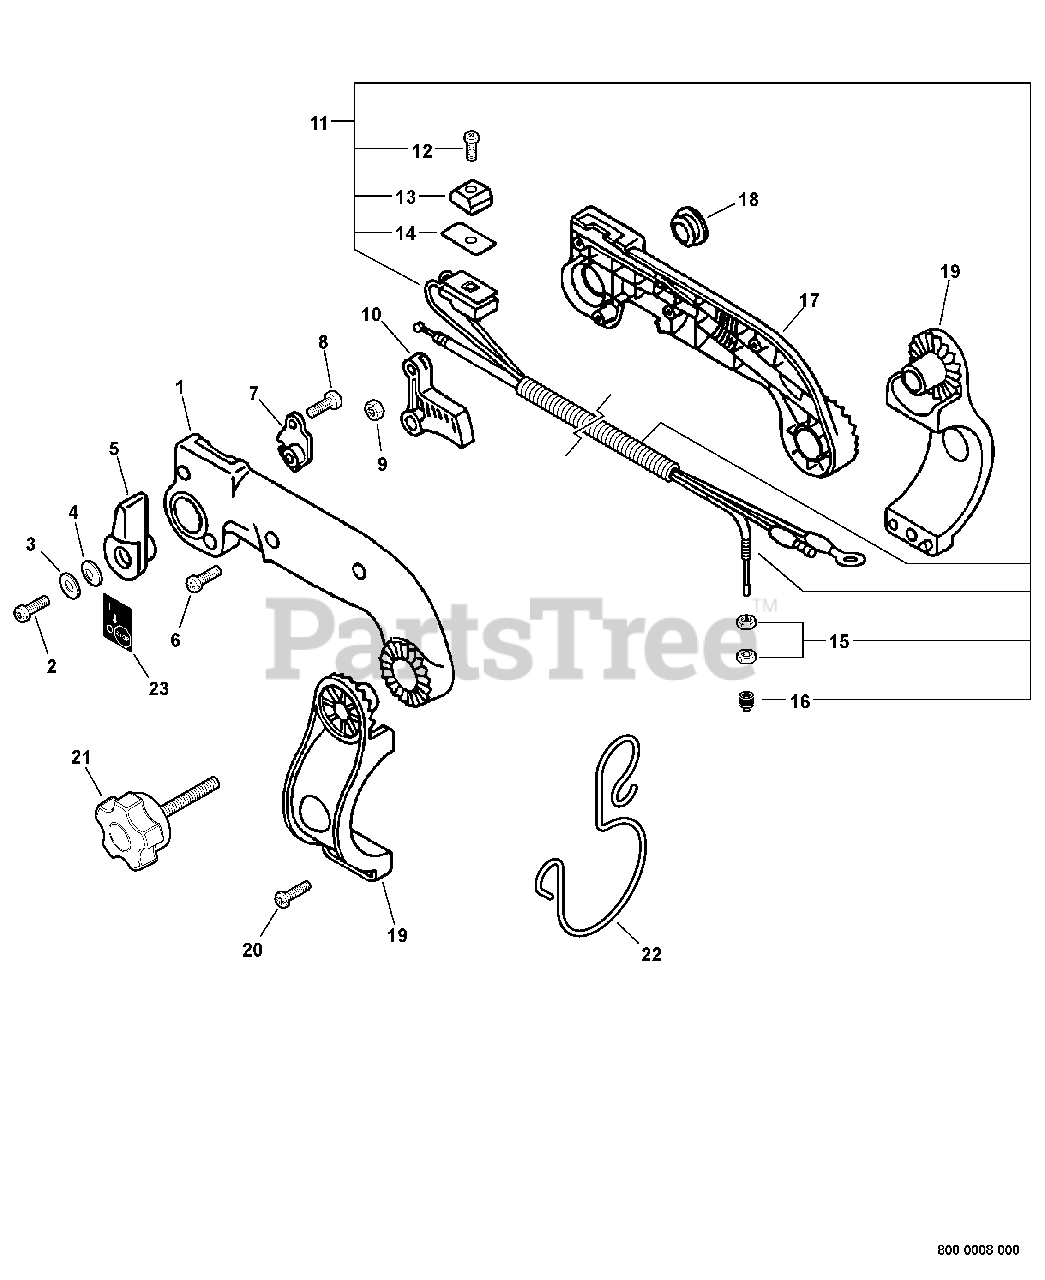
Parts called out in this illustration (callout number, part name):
1	HANDLE, CONTROL - LEFT
2	SCREW - 6X20
3	LOCKWASHER - 6
4	WASHER - 6
5	CONTROL, THROTTLE
6	SCREW - 4X22
7	BRACKET, THROTTLE
8	SCREW - 4X10
9	LOCKNUT - 6
10	TRIGGER, THROTTLE
11	CONTROL CABLE ASSY
12	SCREW - 3X10
13	KNOB, SWITCH - ORANGE
14	COVER, SWITCH - STOP
16	CAP, DUST
17	HANDLE, CONTROL - RIGHT
19	HANDLE BRACKET KIT
20	SCREW - 5X20 -- TAPPING
21	THUMBSCREW
23	LABEL - STOP
